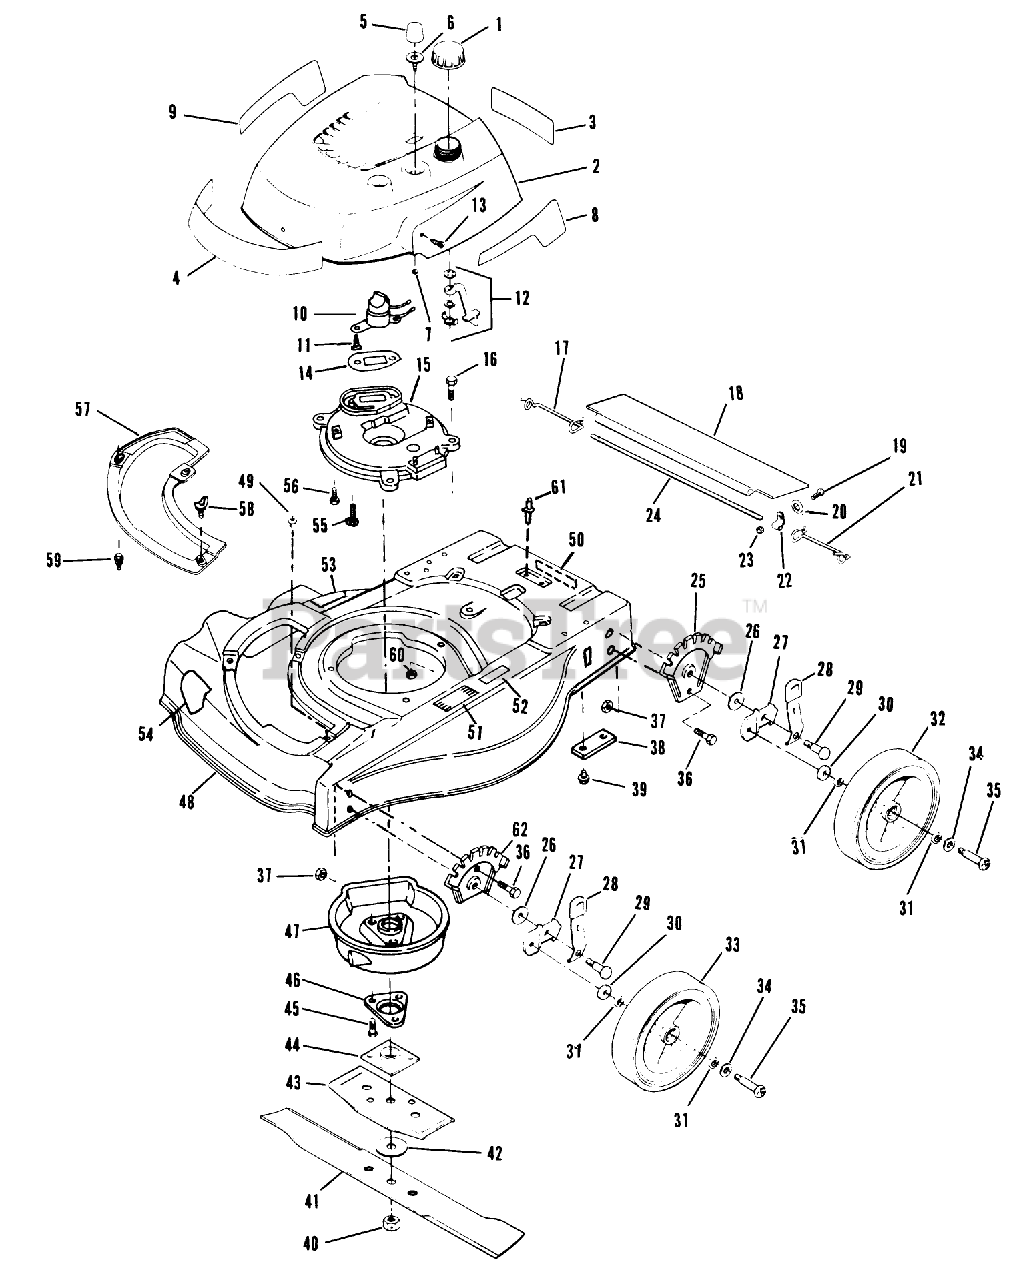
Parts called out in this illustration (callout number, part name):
5	P-BULB LAV-RUB
7	LOCKNUT S
13	SCREW S
15	PLATE,MUFFLER F
16	SCREW
17	SPRING;TRAILING SHIELD RH
20	WASHER F
21	SPRIG T/SHLD ASOC
23	LOCKNUT E
26	WASHER
30	WASHER WROUGHT
31	WASHER
34	SPACER
35	BOLT WHEEL
37	LOCKNUT
39	SCREW
40	NUT-BLADE
42	WASHER
44	PLATE AND COLLAR ASM
45	SCREW
46	SUPPORT F
51	PAD FOOT
55	SCREW V
58	WING SCREW LAWRE
60	NUT-LOCK F
61	Rivet-Serial Plate
62	PLATE HGT ADJ TRO
